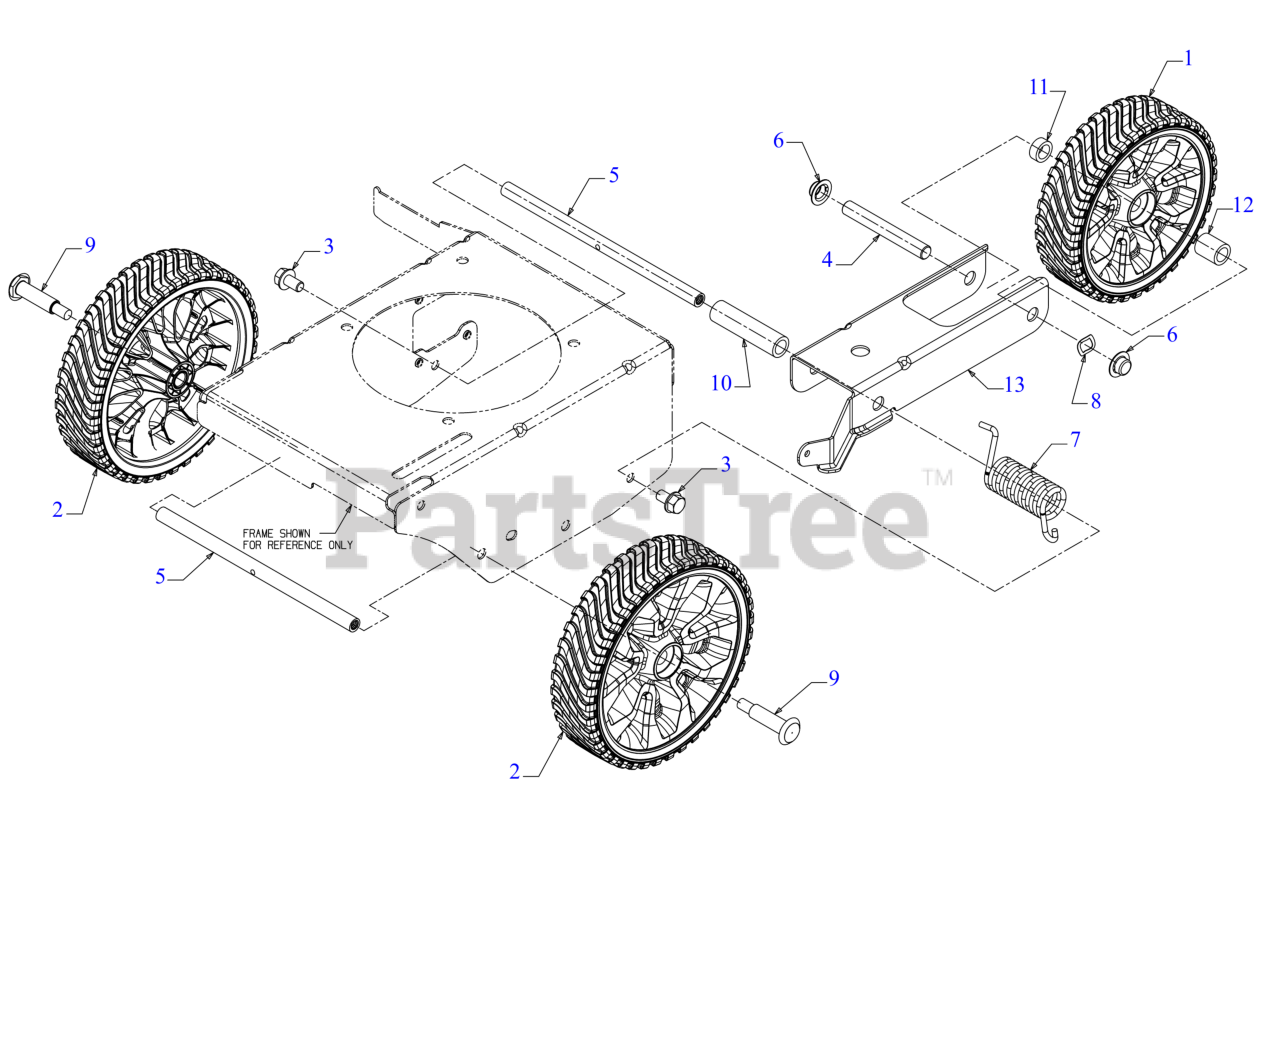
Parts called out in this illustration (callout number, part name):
1	WHEEL ASSEMBLY 7" x 2"
1	Genuine Factory Parts WHEEL ASSEMBLY (7x2x1/2)(GRAY)
2	WHEEL ASSEMBLY 8 x 2 GRAY
2	Troy-Bilt IDLE WHEEL ASSEMBLY (8x2x1/2) (GREY)
3	SCREW 3/8-16X.625 GR 5
4	AXLE SHAFT
5	SPACER .50 x 9.25
7	TORSION SPRING
8	WAVE WASHER
9	SHOULDER BOLT .498 DIA. x 1.64
